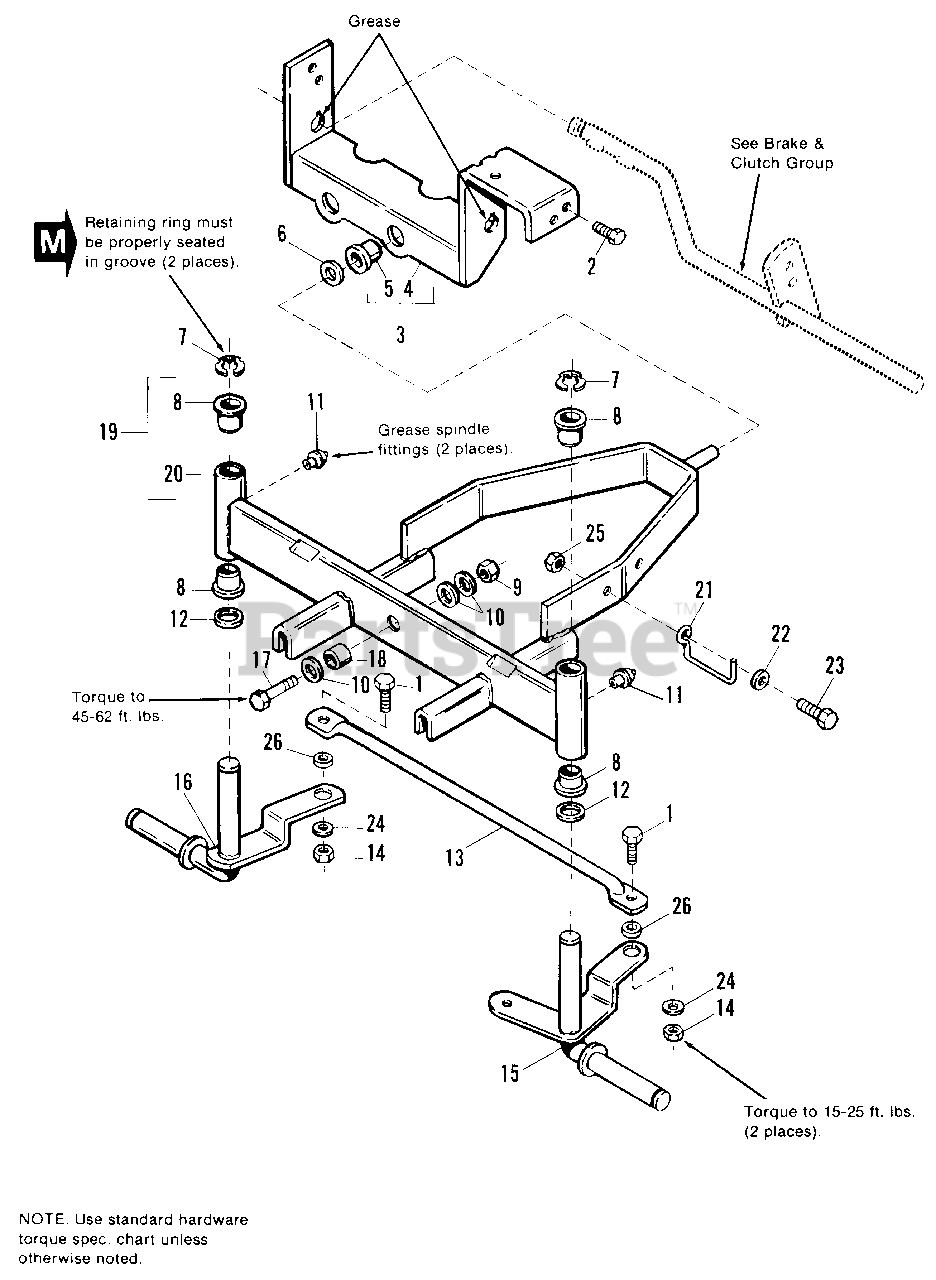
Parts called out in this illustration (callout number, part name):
1	CAPSCREW, 3/8-16 x 1
2	SCREW, Hex, Taptite, 5/16-18 x 3/4
3	SUPPORT ASSY., Axle, Rear w/Bushing
6	WASHER, 3/8
9	LOCKNUT, Hex, 1/2-13
10	WASHER, 9/16
11	FITTING, Grease
12	WASHER
14	LOCKNUT, Hex, 3/8-16
15	SPINDLE ASSY., L.H.
16	SPINDLE ASSY., R.H.
17	CAPSCREW, Hex Hd., 1/2-13 x 3/4
18	SPACER
19	AXLE ASSY., Front (Incl. Ref. Nos. 8 & 20)
21	GUIDE, Drag Link
22	WASHER, 5/16
23	CAPSCREW, Hex Hd., 5/16-18 x 1
24	WASHER
25	NUT, Hex, 5/16-18
